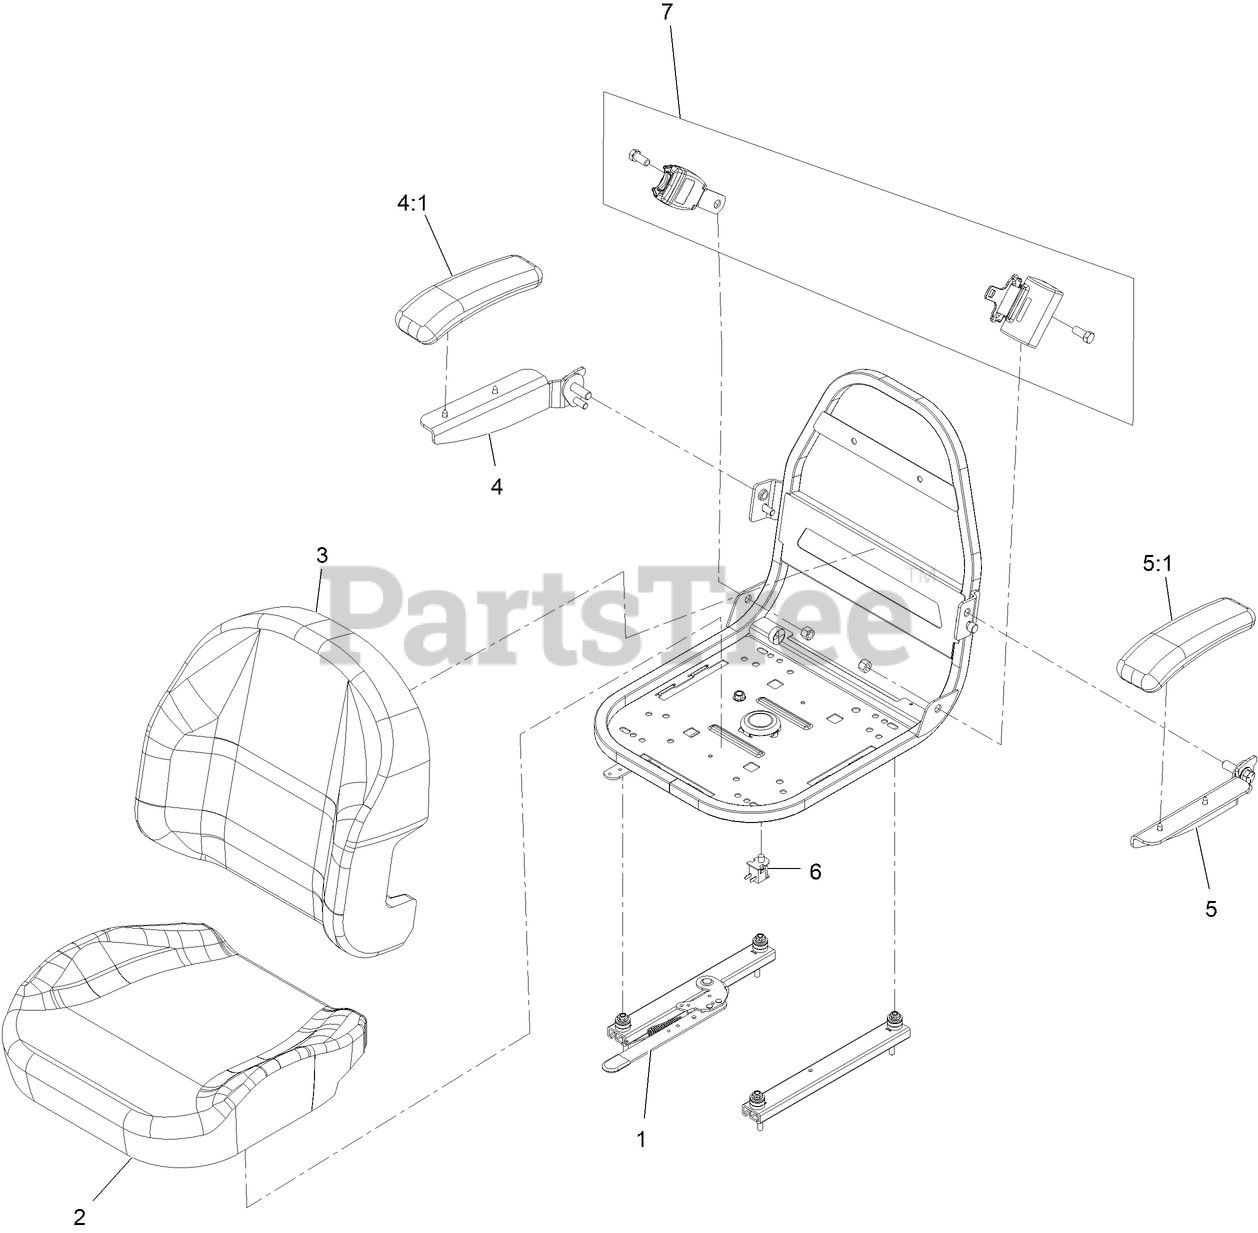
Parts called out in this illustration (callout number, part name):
1	ASM-Track
2	Cushion-Seat Bottom
3	Cushion-Seat Back Exmark
4	RH Arm Rest Kit
4:1	CUSHION-REST, ARM
5	LH Arm Rest Kit
5:1	CUSHION-REST, ARM
6	SWITCH-BAIL
7	KIT-SEAT BELT
